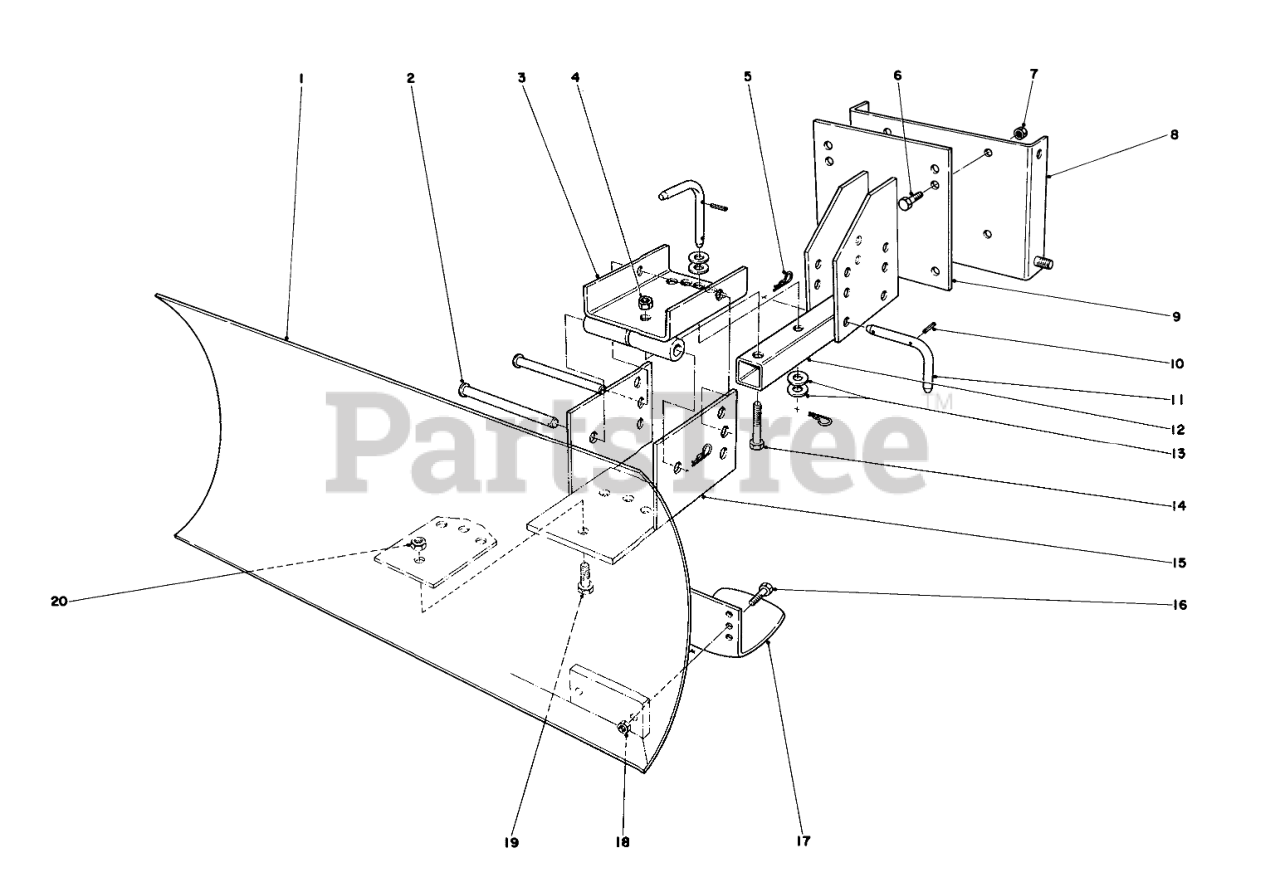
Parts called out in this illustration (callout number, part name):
1	Blade
2	PIN-CLEVIS
3	Swivel Bracket
4	1/2-13 CONELOCK NUT
5	PIN-HAIR
6	SCREW-HH
7	NUT-LOCK, CONE
8	Mounting Plate (Used with 826 & 1132 Units only)
9	Mounting Plate
10	PIN-SPRING
11	Pivot Pin (Incl. Ref. #10)
12	Blade Tongue
13	WASHER-FLAT
14	SCREW-HH
15	Blade Adjustment
16	SCREW-HH
18	NUT-LOCK, CONE
19	SCREW-HH
20	1/2-13 CONELOCK NUT
